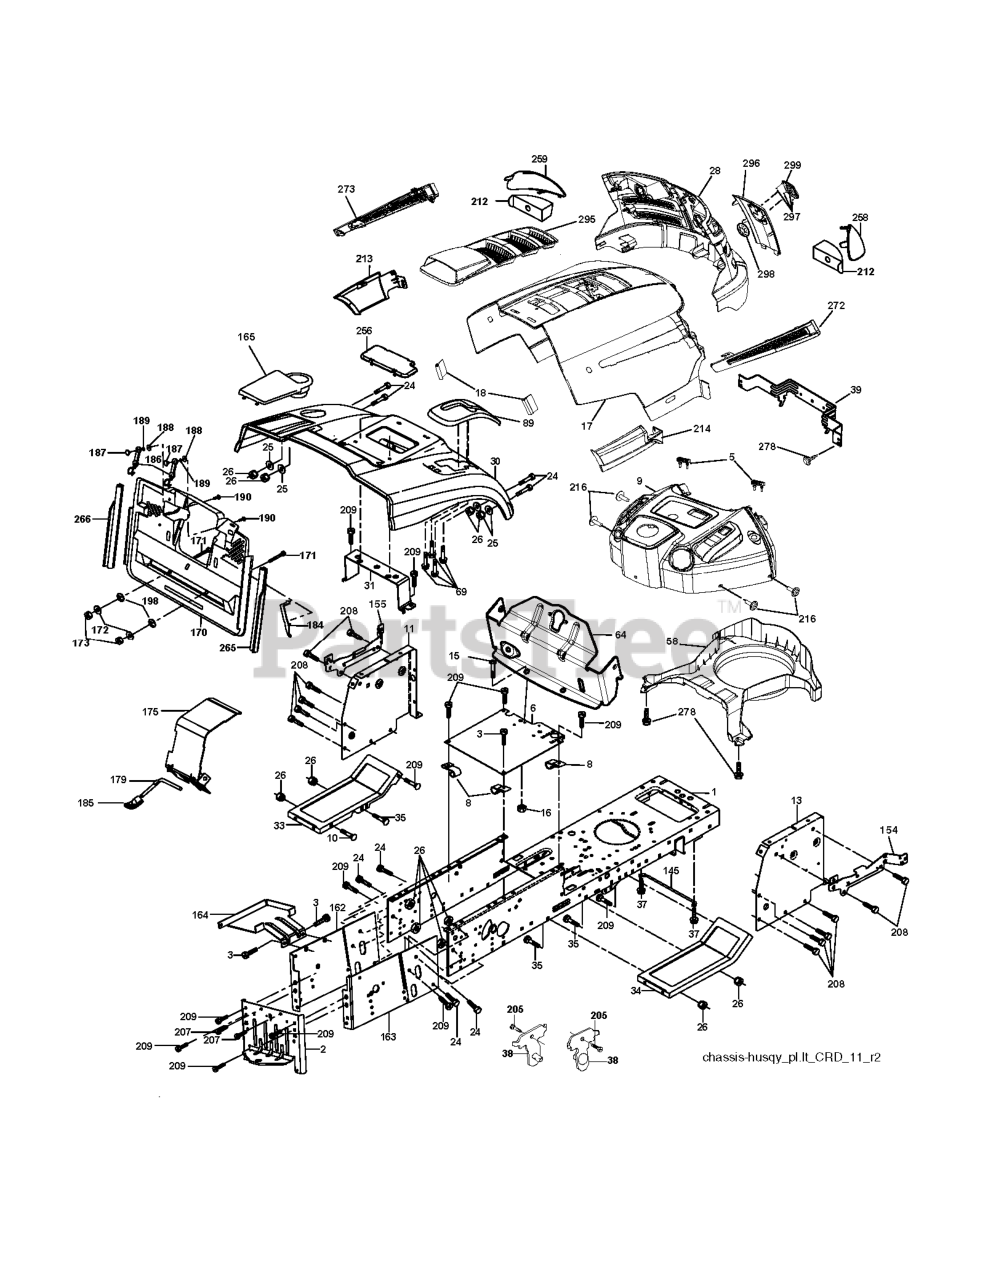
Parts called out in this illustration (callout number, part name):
2	DRAWBAR
3	SCREW 3/8-16X3/4
5	BUMPER DASH
6	PLATE
8	CLIP,INSULATOR
10	BOLT D
11	PANEL.DASH.LH.LTX
13	PANEL ASM, DASH RH
15	Screw, Machine, Truss Head 5/16-18 UNC x 3/4
16	NUT
17	HOOD
18	BUMPER.HOOD.TEX.HUSQVARNA
25	WASHER
26	NUT
28	RP GRILLE/LENS ASM.
30	CONSOLE.CRD.AUTO.GRY
31	BRACKET SUPPORT FENDER
33	FOOTREST PNT LH
34	FOOTREST PNT RH
37	Screw 5/16-18 x 1/2 Hex, Self Tapping 5/16-18 x 1/2
38	BRACKET ASM PIVOT MOWER REAR
39	BRACKET PIVOT
69	SCREW.HI-LO.CONSOLE
89	CONSOLE.CRD.AUTO.GREY.2005
145	ROD PIVOT CHASSIS/HOOD
162	BRACKET
163	BRACKET EXTEN CHASSIS RH CRD
165	RP.COVER.BATTERY.CRD.GREY
172	WASHER
175	DOOR TRAP
179	ROD PIVOT FBI
184	BRACKET.ACTUATOR.BAGGER.SRD
186	LATCH ASSY
187	WELDNUT
189	LOCKWASHER #10
190	SCREW
207	SCREW, 5/16-18 X 1/2
208	SCREW 3/8-16X1/2
209	SCREW, 3/8-16X3/4
212	INSERT REFLECTIVE
213	SKIRT SIDE LH
214	SKIRT SIDE RH
216	SCREW HEXWSHR 1/4-20X3/4
256	COVER FENDER CRD
258	LENS.HUSQVARNA LT.RH
259	LENS.HUSQVARNA LT.RH
265	SEALING
266	SEALING
278	SCREW
295	VENT TOP HOOD
296	TRIM
297	CLIP.RETAINER.TINNER.
298	NUT PUSH M
299	RP LOGO
